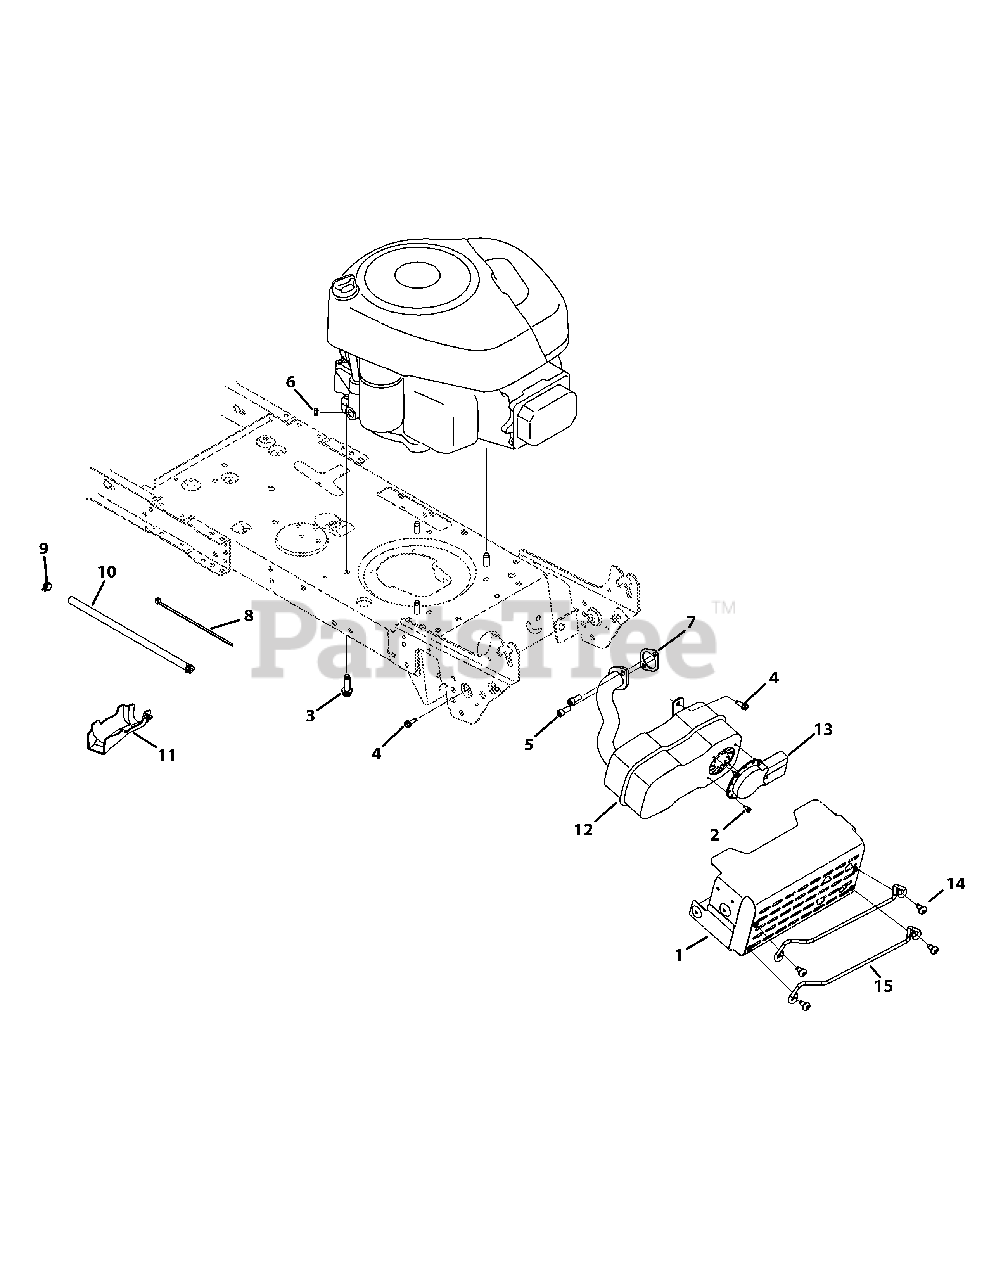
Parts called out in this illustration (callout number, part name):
1	Muffler Shield Assembly
2	Screw, 8-18 x .500
3	Screw, 3/8-16 x 1.0
4	Screw, 1/4-20 x .750
5	Socket Screw, 5/16-18 x .750
6	Sems Nut, 1/4-20
7	Exhaust Gasket, 10 HP Briggs
8	Cable Tie
9	Clamp Hose, .490 diameter
10	Fuel Hose, Low Permeation
11	Oil Drain Sleeve
12	Muffler, Single Inlet
13	Muffler Deflector Long
14	Pan Torx Screw 1/4
15	Muffler Guard Rod
